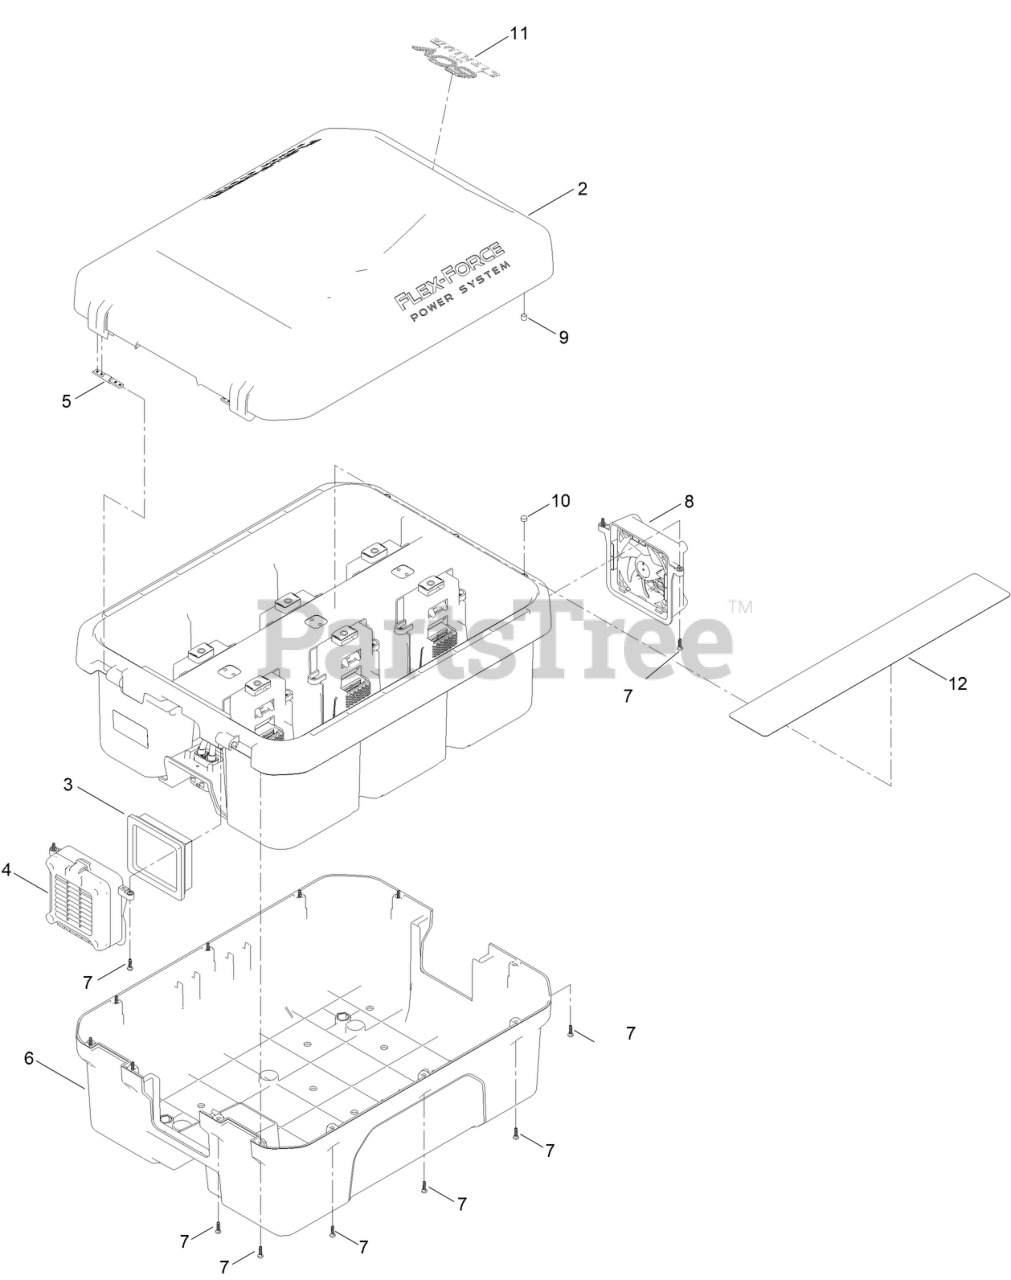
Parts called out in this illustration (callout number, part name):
2	COVER-BOX, BATTERY
3	FILTER-AIR
4	HOUSING-FILTER
5	HINGE-BOX ASM, BATTERY
6	BOX-BATTERY, OUTER
7	SCREW-PLASTIC 4MMX14MM, GLOBE
8	FAN-ASM
9	MAGNET-LID, BATTERY BOX
10	MAGNET-BASE, BATTERY BOX
11	DECAL-60V, LITHIUM
12	DECAL-LITHIUM
